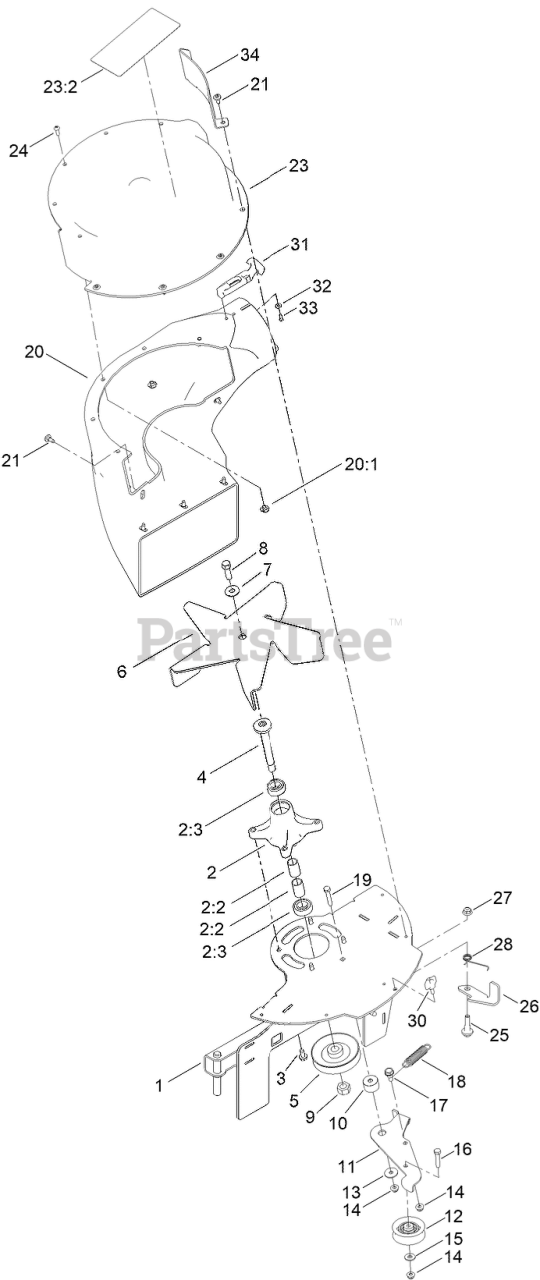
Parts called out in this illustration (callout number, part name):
1	FRAME-BLOWER
2	SPINDLE ASM
2:2	SPACER
2:3	BEARING-BALL
3	SCREW-HWHTF
4	SHAFT - SPINDLE
5	PULLEY-BLOWER
6	FAN-BLOWER
7	WASHER-BELLEVILLE
8	SCREW-HH
9	NUT-HEX
10	SPACER-IDLER ARM
11	IDLER ARM, BLOWER
12	PULLEY-IDLER, FLAT
13	WASHER-PIVOT
14	NUT-HF
15	WASHER-FLAT
16	SCREW-HH
17	BOLT SHOULDER
18	SPRING-PEDAL, RETURN
19	SCREW-HH
20	BLOWER CHUTE ASM
20:1	CHUTE-BLOWER
21	SCREW-SHOULDER
23	BLOWER COVER ASM
23:2	DECAL-DANGER
24	SCREW-PRH
25	BOLT-SHOULDER
26	LATCH-BLOWER
27	NUT-HF, NI
28	SPRING-TORSION
31	LATCH-RUBBER
32	WASHER-PLAIN
33	SCREW-HSBH
34	GUARD-BLOWER
